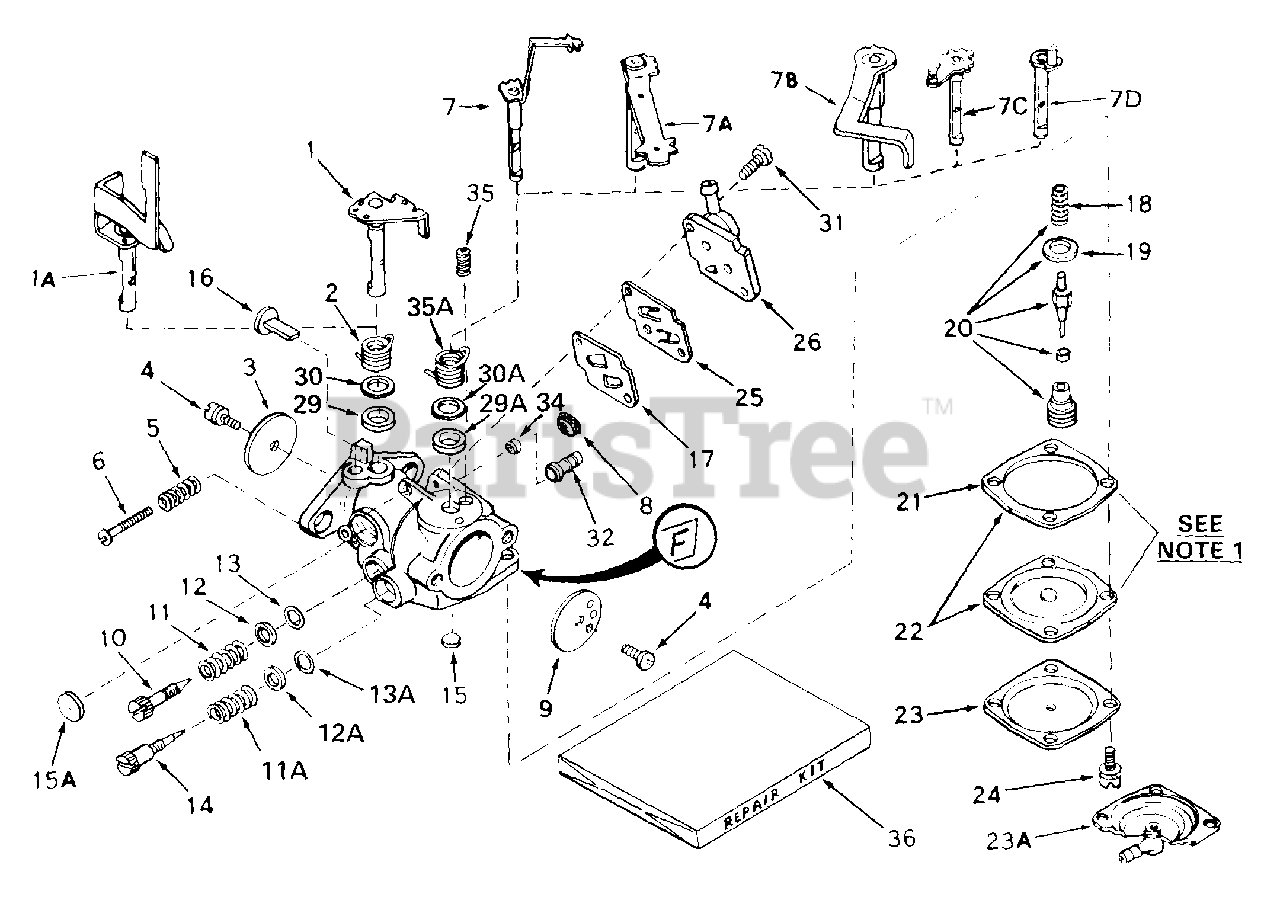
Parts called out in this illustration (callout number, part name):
1	"Shaft & Lever Assy., Throttle
2	Spring, Throttle return
3	Shutter, Throttle
4	Screw, Throttle & Choke shutter
5	Spring, Idle screw regulating
6	Screw, Idle regulating
7C	Shaft & Lever Assy., Choke
9	Shutter, Choke
10	Screw, Idle adj.
11	Spring, Adj. screw
11A	Spring, Adj. screw
12	Washer, Adj. screw
12A	Washer, Adj. screw
13	"O" Ring, Adj. screw
13A	"O" Ring, Adj. screw
14	Screw, Main adj.
15	Plug, Welch
15A	Plug, Welch
18	Spring, Valve
19	Gasket, Valve seat
20	Inlet Needle, Seat, Spring & Gasket A ssy.
21	Gasket, Diaphragm
22	Diaphragm Assy.
23A	Cover Assy., Diaphragm
24	Screw, Diaphragm cover
32	Fitting, Fuel inlet
34	Valve, Check
35	Spring, Choke positioning
36	Repair Kit
